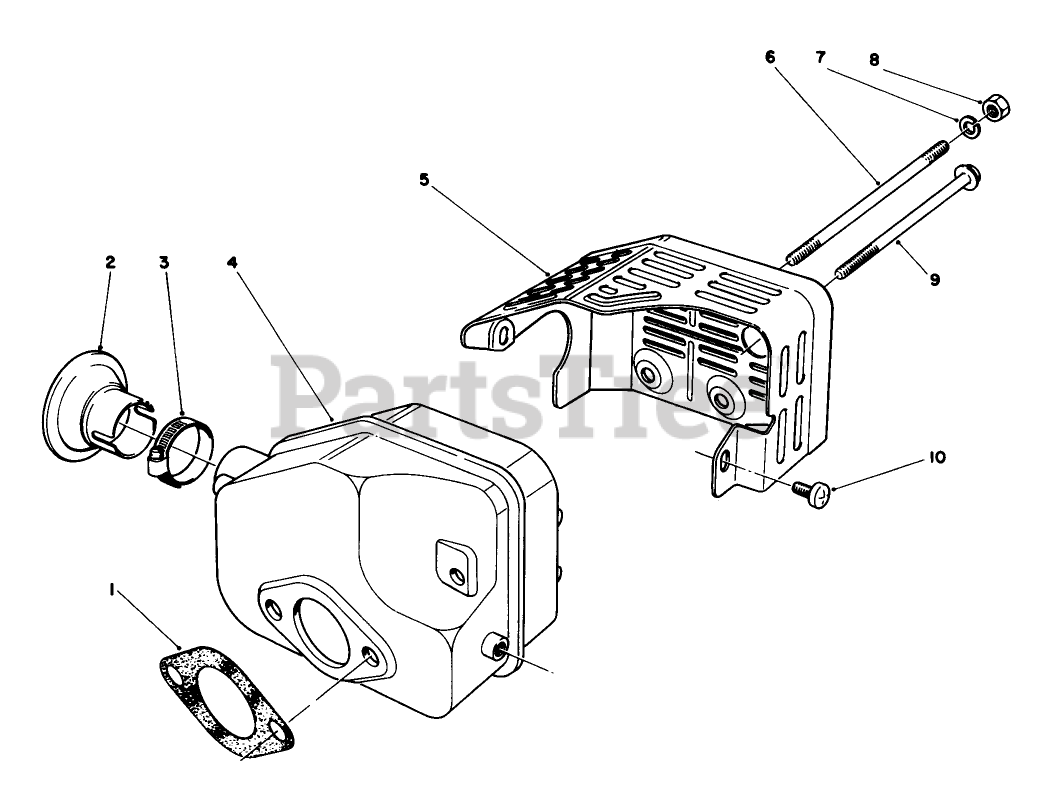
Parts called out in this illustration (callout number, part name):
1	GASKET
3	Clamp
5	COVER-MUFFLER
7	WASHER-LOCK
